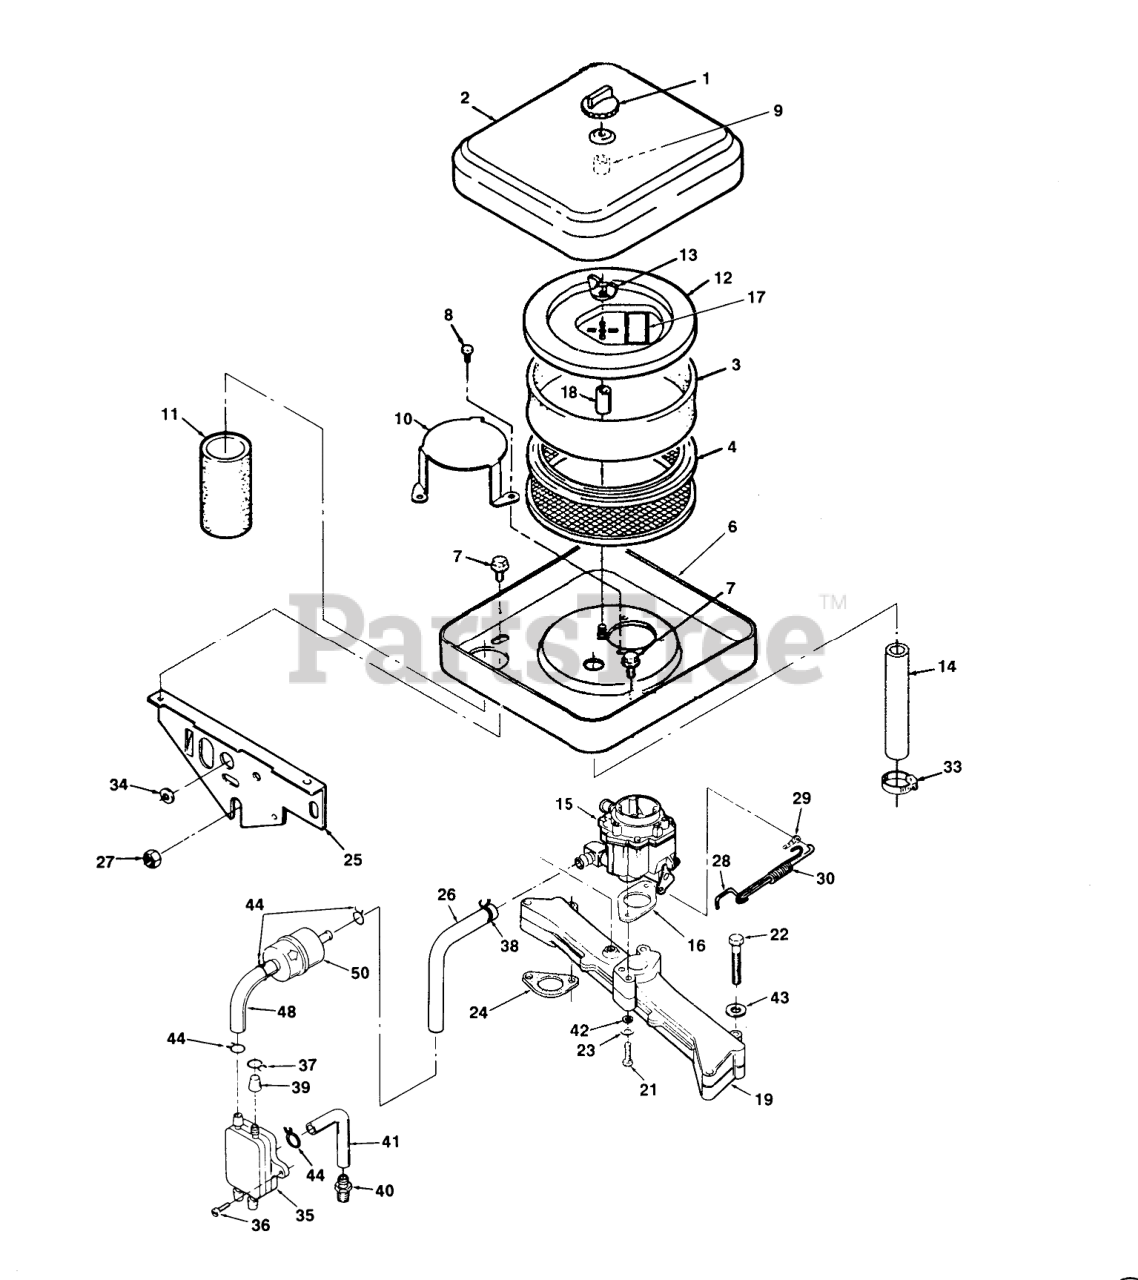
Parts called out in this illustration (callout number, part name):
1	Knob
2	COVER-AIR CLEANER
3	WRAPPER-AIR CLEANER ELEMENT
4	ELEMENT-AIR CLEANER
6	HOUSING-AIR CLEANER
7	SCREW-TAPPING
8	Screw-HWH
9	SPACER-RUBBER
10	PLATE-AIR DEFLECTOR
11	TUBE-AIR INTAKE
12	ELEMENT COVER KIT
13	1/4-20 WING NUT
14	HOSE-BREATHER
15	Carburetor
16	GASKET-CARBURETOR
17	DECAL-PERIODIC MAINTENANCE
18	SPACER-AIR CLEANER STUD
19	MANIFOLD - INTAKE
21	HEX HD CAP SCR
22	Screw-Hex Hd Cap
23	WASHER-FLAT
24	GASKET-MANIFOLD TO BLOCK
25	SUPPORT-AIR CLEANER
26	HOSE - FUEL
28	ROD-GOV CONTROL
30	Spring-Governor Rod
33	CLAMP-HOSE, BREATHER
34	GROMMET
35	Pump-Fuel (Incl. Hose Clamp & Fuel Cap)
37	CLAMP
39	CAP-FUEL OUTLET
40	FITTING-BARB
41	HOSE-VACUUM
42	WASHER-FLAT
43	WASHER-FLAT
44	CLAMP-HOSE
50	FILTER-FUEL
